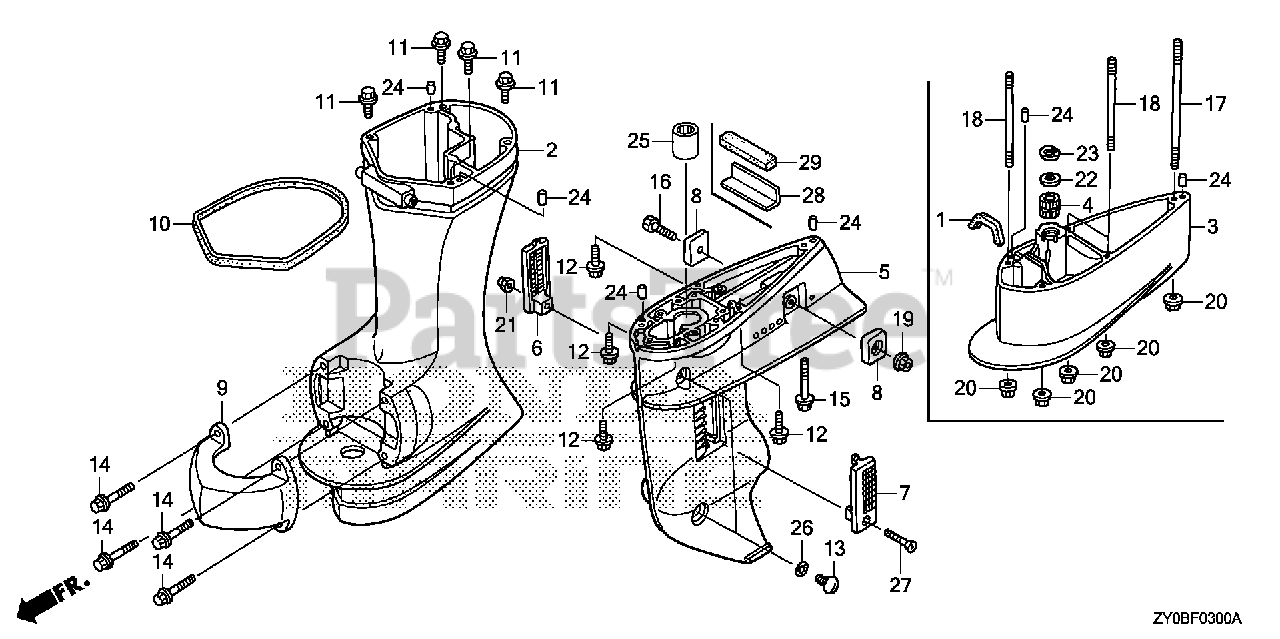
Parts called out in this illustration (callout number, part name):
2	CASE, EXTENSION *NH282MU* (L) (OYSTER SILVER METALLIC-U)
5	CASE, GEAR *NH282MU* (OYSTER SILVER METALLIC-U)
6	SCREEN, R. WATER
7	SCREEN, L. WATER
8	METAL, ANODE
9	HOUSING, MOUNTING (LOWER) *NH282MU* (OYSTER SILVER METALLIC-U)
10	RUBBER, COVER (LOWER)
11	BOLT, FLANGE (8X35)
12	BOLT, FLANGE (6X23)
13	BOLT, OIL CHECK
14	BOLT, FLANGE (6X20)
15	BOLT, FLANGE (6X75)
16	BOLT, HEX. (6X25)
19	NUT, SELF-LOCK (6MM)
21	NUT, SELF-LOCK (5MM)
24	PIN, DOWEL (6X10)
25	BEARING, NEEDLE (15X22X20)
26	O-RING (6.9X1.45)
27	SCREW, OVAL (5X28)
